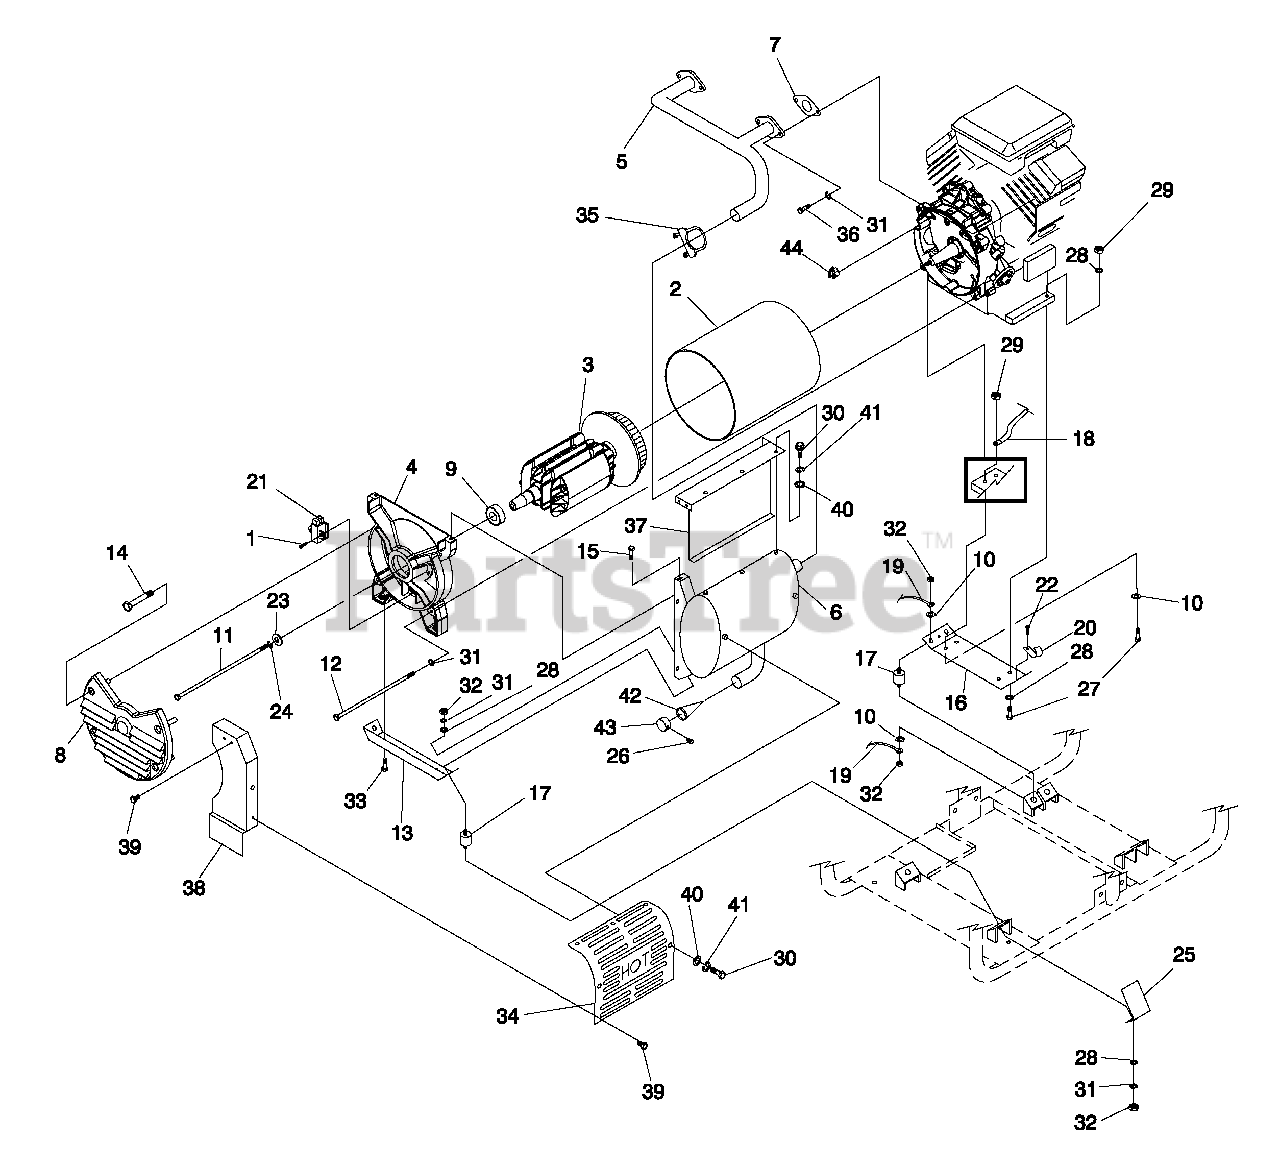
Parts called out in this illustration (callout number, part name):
1	SCREW HHTT M5-0.8 X 16
2	STATOR 15KW
3	ASSEMBLY, ROTOR WITH FAN 15KW
4	CARRIER, REAR BEARING
5	EXHAUST MANIFOLD
6	MUFFLER
7	GASKET, EXHAUST
8	COVER, ALTERNATOR AIR IN
9	BEARING
10	5/16 SPECIAL LOCK WASHER
11	SCREW IHHC 3/8-24 X 15.50 G5
12	SCREW IHHC M8-1.25 X 400 G8.8
13	BRACKET, ALT MOUNTING
14	SCREW HHTT #10-32 X 1.75
15	SCREW HHTT M8-1.2 X 20
16	ENGINE MOUNTING PLATE
17	RUBBER MOUNT
18	BATTERY CABLE, BLACK
19	EARTH STRAP 3/8X 3/8
20	CLIP-J VINYL COAT .625 ID
21	ASSEMBLY, BRUSH HOLDER
22	SCREW TAP-R #10-32 X 9/16
23	WASHER FLAT 3/8 ZINC
24	WASHER LOCK 3/8
25	SHIELD, RUBBER MOUNT
26	SCREW HHTT M4-0.7 X 8
27	SCREW HHC M8-1.25 X 50 G8.8
28	WASHER FLAT 5/16 ZINC
29	NUT LOCK HEX M8-1.25 NYLON INSERT
30	SCREW HHC M6-1.0 X 12
31	WASHER LOCK M8-5/16
32	NUT HEX 5/16-18 STEEL
33	SCREW TAPTITE 3/8-16 X 3/4 BP
34	SHIELD, MUFFLER HEAT
35	U-BOLT & SADDLE
36	SCREW SHC M8-1.25 X 18
37	PANEL, MUFFLER BOX BACK
38	PANEL, MUFFLER BOX END
39	SCREW HHTT M6-1.0 X 12
40	WASHER FLAT M6-1/4
41	WASHER LOCK M6-1/4
42	SPARK ARRESTOR SCREEN
43	RETAINER, SPARK ARREST SCREEN
44	PLUG, GEARCOVER ADAPTOR
